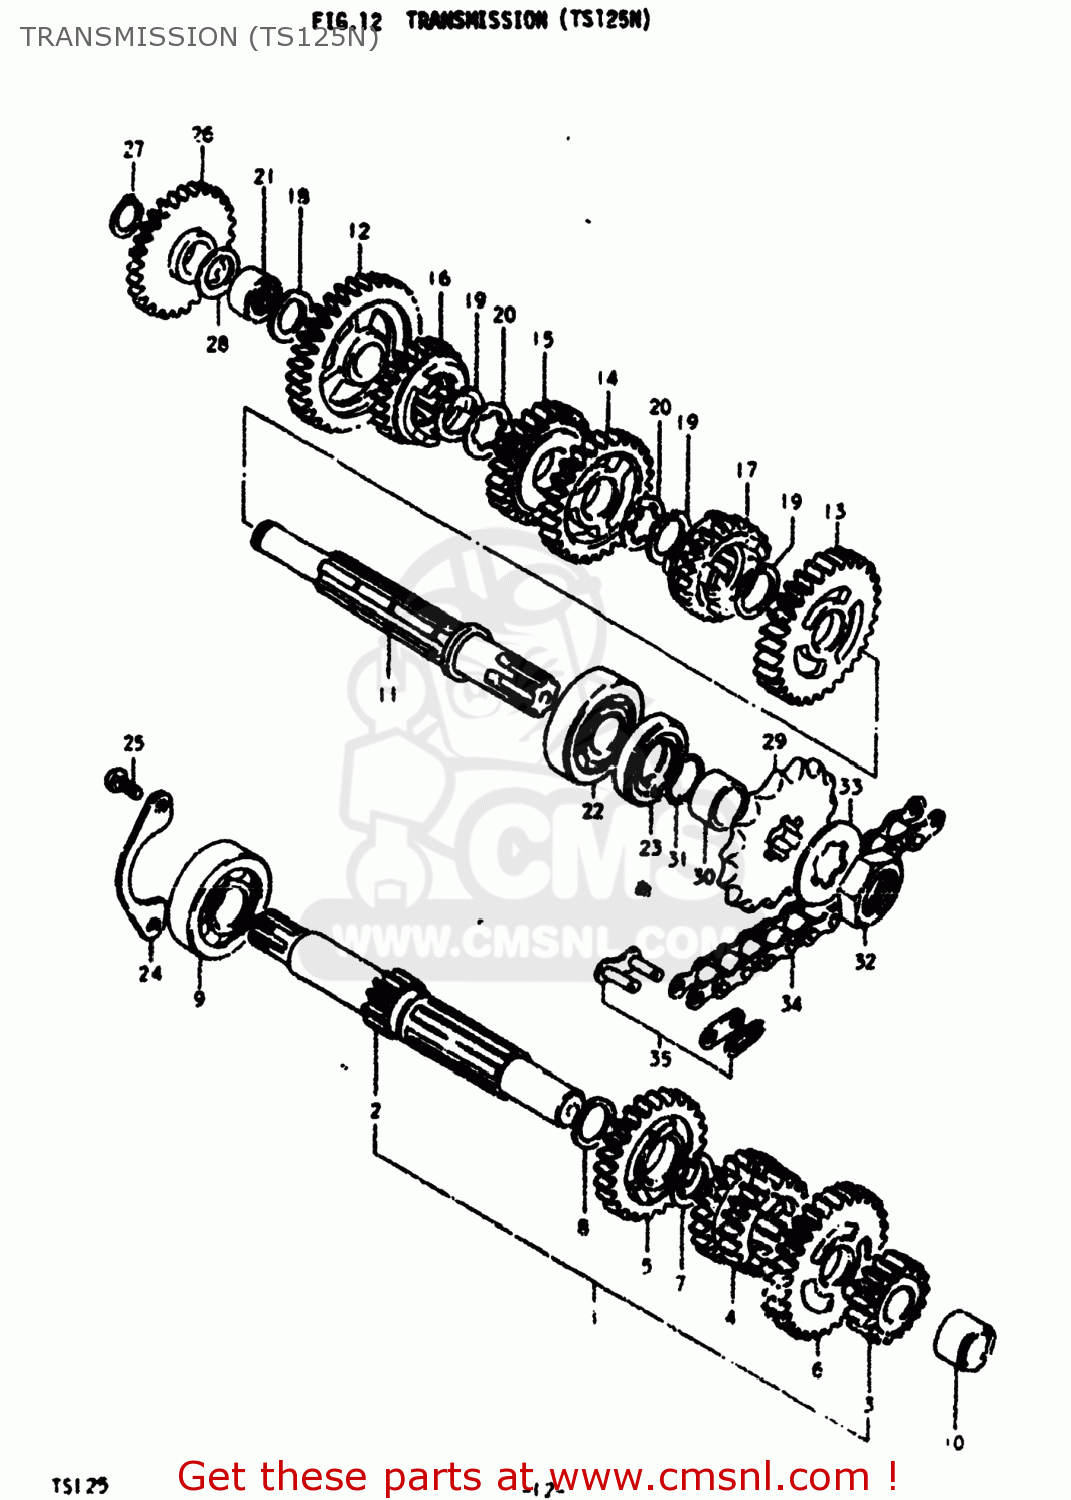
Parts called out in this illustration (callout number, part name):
1	SHAFT ASSEMBLY,COUNTER
2	SHAFT,COUNTER
3	GEAR,SECOND DRIVE
4	GEAR,THIRD/FOURTH DRIVE
5	GEAR,FIFTH DRIVE
6	GEAR,SIXTH DRIVE
7	CIRCLIP
8	WASHER
9	Bearing
10	BUSH(15X22X15)
11	SHAFT,GEAR SHIFT
12	GEAR,1ST DRIVEN
13	GEAR,SECOND DRIVEN
14	GEAR,THIRD DRIVEN
15	GEAR,FOURTH DRIVEN
16	GEAR,FIFTH DRIVEN
17	GEAR,SIXTH DRIVEN
18	WASHER,THRUST
19	CIRCLIP
20	WASHER,LOCK
21	BEARING(15X22X12)
22	Bearing
23	SEAL,OIL(25X40X7)
24	RETAINER,CNTR SHAFT BEARING
25	SCREW 6X12
26	GEAR,KICK STARTER IDLE
27	CIRCLIP,15MM
28	WASHER,THRUST
29	SPROCKET,ENGINE
30	SPACER(20X25X12.5)
31	O RING(D:2,ID:70)
32	NUT
33	WASHER,LOCK
34	CHAIN ASSEMBLY,DRIVE
35	JOINT ASSEMBLY,CHAIN
